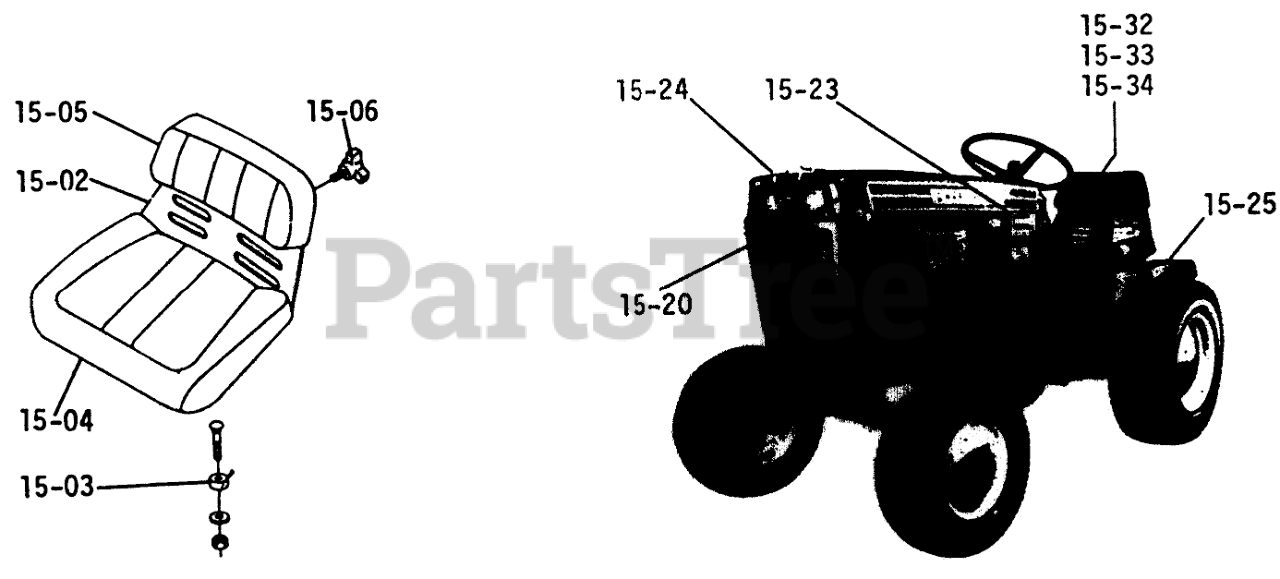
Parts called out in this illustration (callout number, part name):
15-04	BULLT 281
15-05	BULLT 281
15-23	Decal-Raider 10
15-33	Decal Shift Pattern
